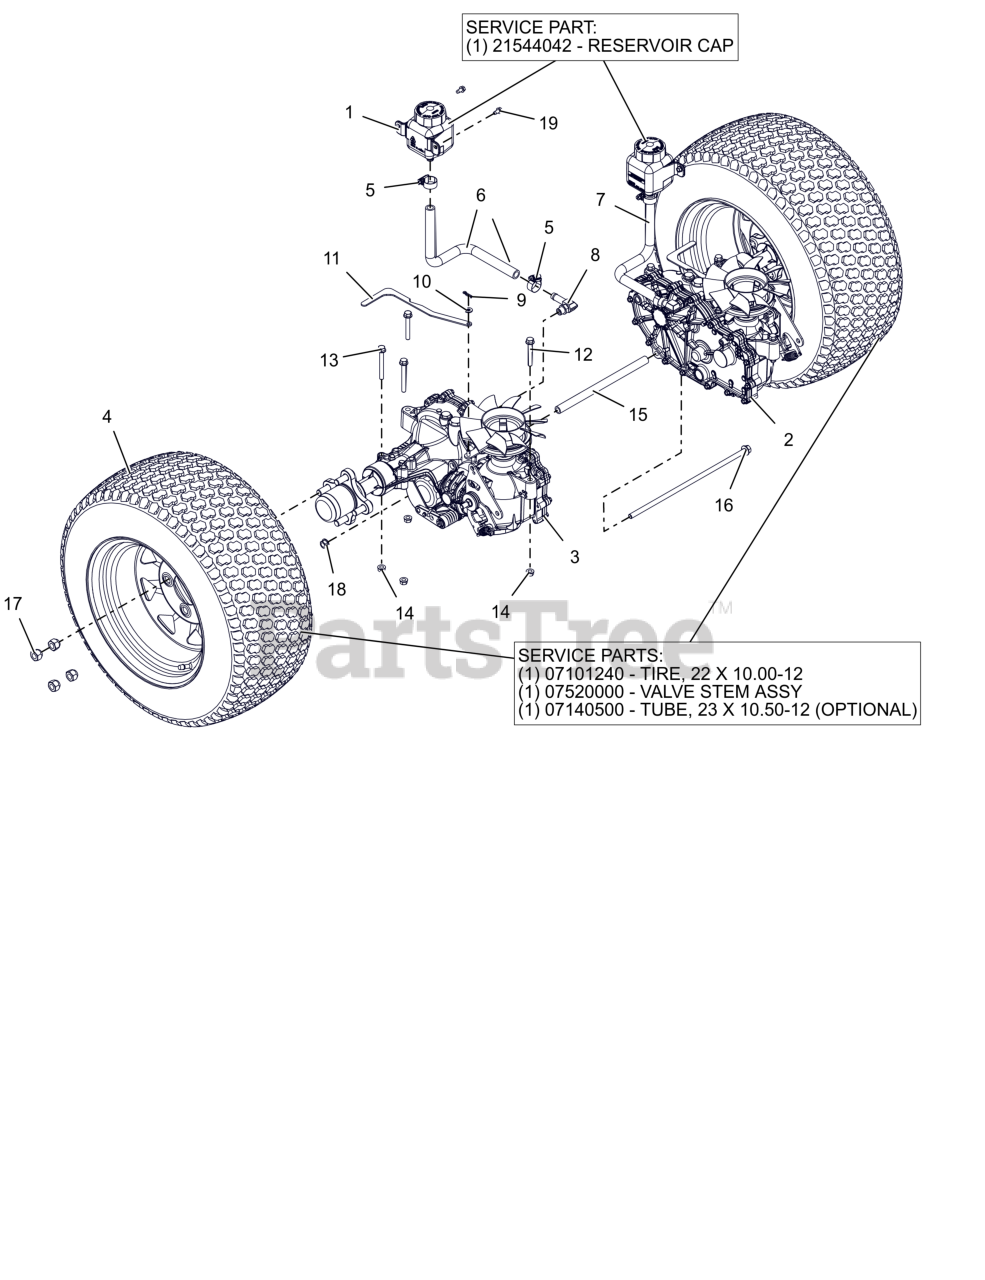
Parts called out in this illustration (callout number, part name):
1	TANK, EXPANSION
1	CAP, HYDRO RESERVOIR REPLAC.
2	TRANSAXLE, ZT3100 - LH
3	TRANSAXLE, ZT3100 - RH
4	ASM, WHL/TIRE 22X10-12 LG BLK
4	TIRE, 22X10.00-12
4	VALVE STEM ASS'Y
4	TUBE 22,23&24X8.50/9.50/10.00/10.50/12.00-12
5	CLAMP,.88 DIA. HOSE
6	HOSE, FORMED EXPANSION -HD RH
7	HOSE, FORMED EXPANSION -HD LH
8	FITTING, HYD (90 DEG)
9	PIN, HAIR #225 .072X1.09
10	WSHR,FLT .281X.625X.065 ZCC
11	BRKT, VALVE DUM
12	BLT,HEX-FLG .31-18X2.25 G5 ZCC
13	BLT,HEX-FLG .31-18X2.75 G5 ZCC
14	NUT,LK-CTR-FLG .31-18 GF ZCC
15	SPCR, TRANSAXLE .406 ID X .630 OD X 9.95LG (BLACK)
16	BLT, HEX-FLG 0.375-16X13 GR5 ZC120
17	NUT, WHEEL .50-20 ZCC
18	NUT-LK-TOP-FLG .38-16 ZC120
19	SCR-TAP .25-20X.50 HWH ZCC
